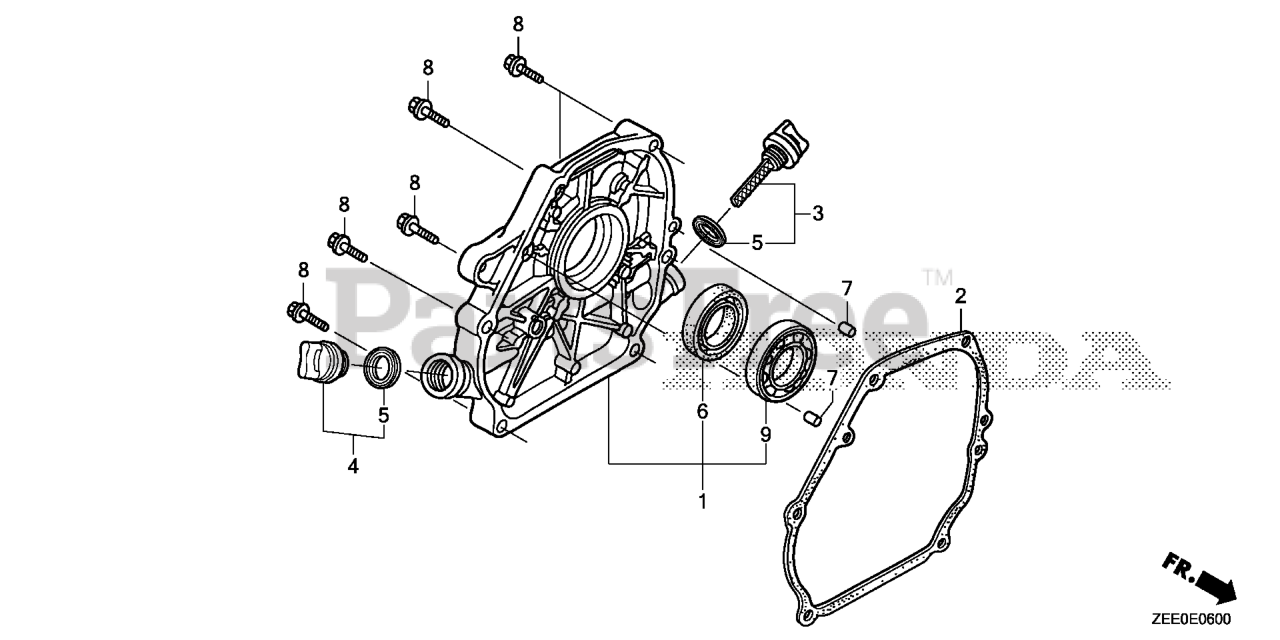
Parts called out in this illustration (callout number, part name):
1	COVER ASSY., CRANKCASE
2	GASKET, CASE COVER (NON-ASBESTOS)
2	GASKET, CASE COVER (NINGBO SIL GASKET)
3	CAP ASSY., OIL FILLER
4	CAP ASSY., OIL FILLER
5	GASKET, OIL FILLER CAP
6	OIL SEAL (25X41X6)
6	OIL SEAL (25X41X6) (ARAI) (NOT AVAILABLE)
7	PIN A, DOWEL (8X14)
8	BOLT, FLANGE (8X32)
9	BEARING, RADIAL BALL (6205)
